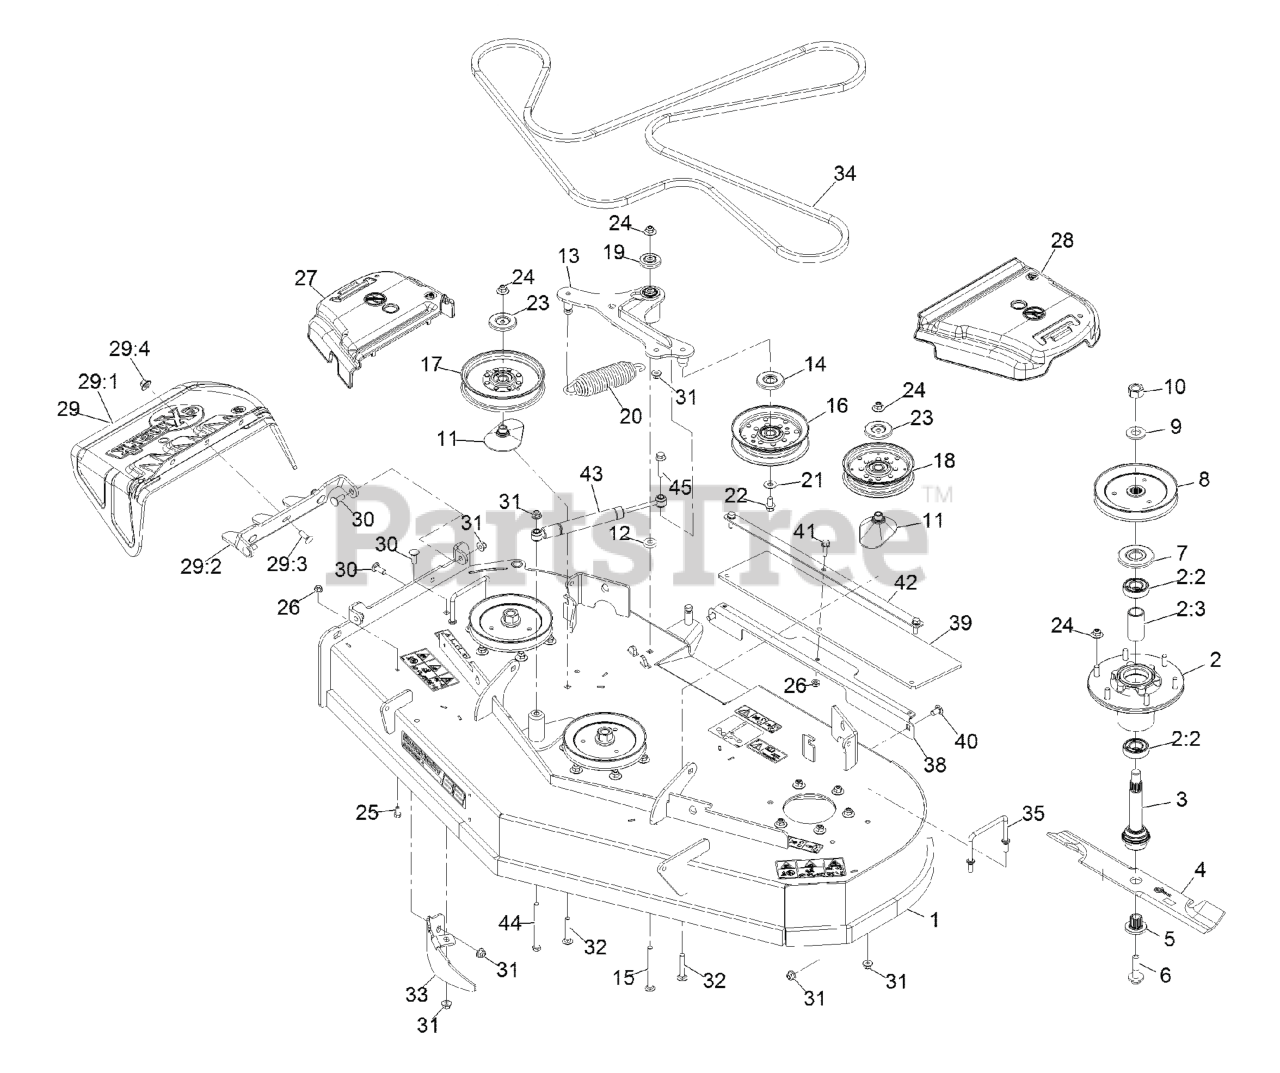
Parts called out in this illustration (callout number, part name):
1	ASM, DECK W/ DECALS, 52
2	ASM-CUTTER HSG WITH BEARINGS
2:2	BEARING-BALL
2:3	SPACER-BEARING
3	ASM-SPINDLE AND SEAL
5	BUSHING,SPLINED
6	SCREW,SEMS 1/2-20 X 2.19
7	GUARD,BEARING TOP .989
8	SHEAVE,BLADE DRIVE 6.50
10	NUT-HEX
11	SPACER-PULLEY
13	ASM-DECK IDLER
14	SHIELD-GUARD, DUST
15	SCREW-CARR
16	IDLER-PULLEY, FLAT
17	IDLER-PULLEY, FLAT 6.00X1.00
18	PULLEY-IDLER, FLAT
19	GUARD-TOP
20	SPRING-EXTENSION
21	WASHER-FLAT
22	SCREW-HHF
23	SHIELD-DUST
24	Nut-Nyloc 3/8-16 Flg
25	SCREW-HH
26	NUT-HF, NI
27	COVER-BELT, RH
28	COVER-BELT, LH
29	ASM,DISCHARGE CHUTE
29:1	CHUTE,DISCHARGE
29:2	BRACKET,DISCHARGE CHUTE
29:3	SCREW-CARR
29:4	Nut-Nyloc 3/8-16 Flg
30	SCREW-CARR
31	NUT-HF, NI
32	Bolt-Carriage 3/8-16 X 2 1/4
33	BAFFLE-DOGLEG, LZ-VT52
34	BELT, 5V
35	WIREFORM-COVER
38	BRKT, HEAT DEFLECTOR
39	SHIELD, HEAT
40	SCREW-CARR
41	SCREW-HHF
42	BRKT-HEAT DEFLECTOR, TOP
44	SCREW-HH
45	SCREW-HHF
